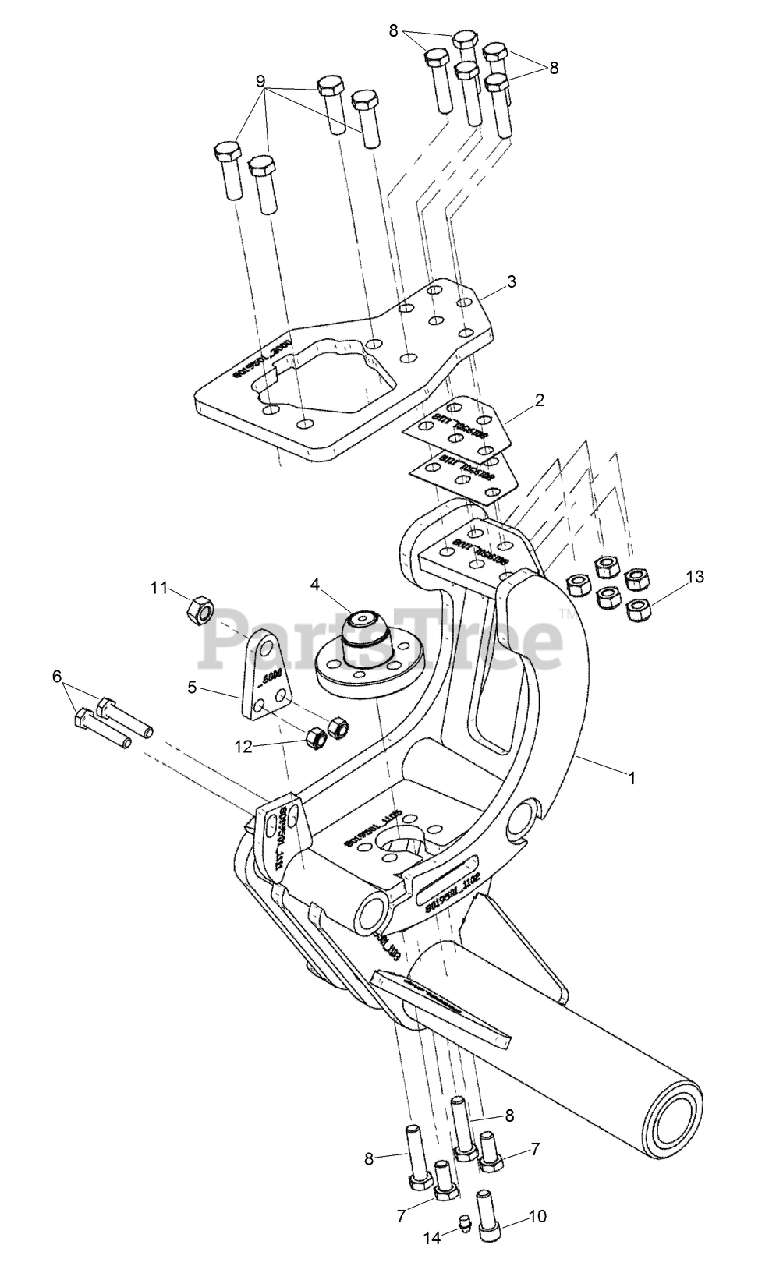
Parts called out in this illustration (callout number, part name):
1	WELDMENT - Right Front Frame Mount
2	PLATE - Shim
3	PLATE - Mounting, Top
4	PIN-KING, TRACKS
5	BRACKET - Direction
6	BOLT - Hex Hd, M12 - 1.75 x 60 mm
7	BOLT - Hex Hd, M14 - 2.00 x 30 mm
8	BOLT - Hex Hd, M14 - 2.00 x 60 mm
9	SCREW-FLANGE
10	SCREW-HSH
11	NUT-HHF
12	NUT-HHF, LOCK
13	NUT - Hex M14 - 2.0
14	ZERK - Grease Fitting, M10 x 1.0 Straight
